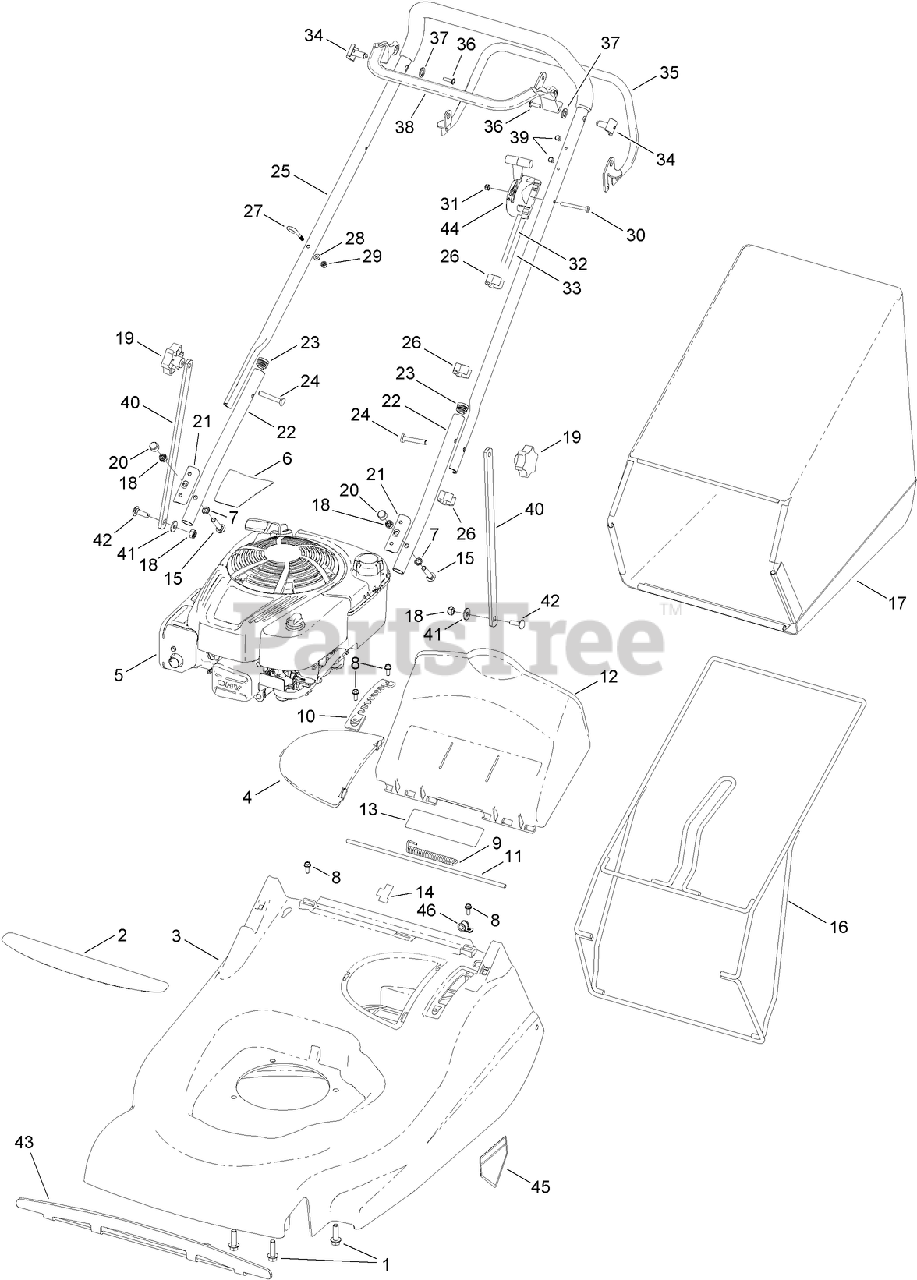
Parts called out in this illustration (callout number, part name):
1	SCREW-TAPTITE, UNC
2	DECAL-DECK
4	COVER-BATTERY
5	ENGINE-BRIGGS, 121Q020130F1
6	DECAL-ENGINE
7	GRIP-FIX
8	SCREW-TAPTITE
9	SPRING-DEFLECTOR
10	RATCHET-PLATE, HOC
11	ROD-DEFLECTOR
12	DEFLECTOR-REAR
13	DECAL-SAFETY
14	DECAL-HOC
15	BOLT-COACH
16	FRAME-GRASSBAG
17	GRASSBAG-FABRIC
18	NUT-HEX, NI
19	KNOB-HANDLEBAR
20	CAP-NUT
21	PLATE-CLAMP, HANDLEBAR
22	HANDLEBAR-LOWER
23	PLUG-TUBE
24	BOLT
25	HANDLEBAR-UPPER
26	GUIDE-CABLE
27	GUIDE-ROPE
28	WASHER-PLAIN
29	NUT-NYLOC
30	SETSCREW
31	NUT-NYLOC
32	CABLE-ENGINE, BRAKE
33	CABLE-CLUTCH
34	PIN-PIVOT
35	LEVER-CLUTCH
36	SCREW
37	WASHER-NYLON
39	FASTENER-DRIVE
40	BRACE-HANDLEBAR
41	WASHER
42	BOLT-COACH
43	BAR-BUMP, PLATE
44	CONTROL-SPEED, ENGINE
45	DECAL-DANGER
46	CLIP-CABLE
